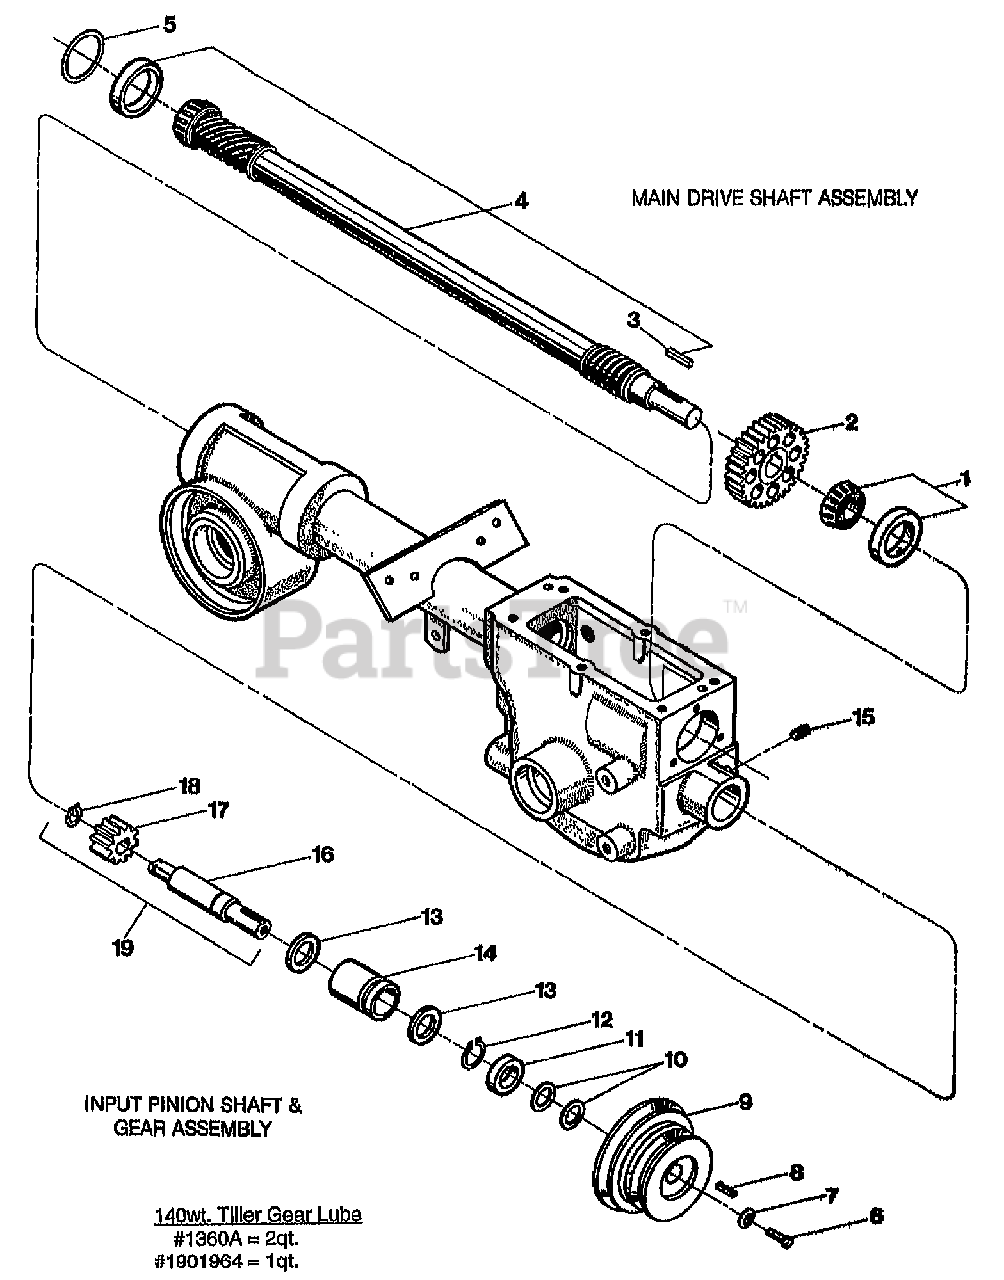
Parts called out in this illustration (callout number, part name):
1	KIT-BRG CONE & RACE-DRIVESHAFT
2	GEAR-SPUR 30 TEETH
3	KEY-.188 SQX1.0
4	KIT-DRIVESHAFT
5	SHIM-1.75X1.5X.01
5	SHIM-1.75X1.5X.03
5	SHIM-1.75X1.5X.005
6	SCR-HH 5/16-24X.75 G5 ZP
7	WASHER-.827X.331X.098 (disc spring, concave surface faces pulley)
8	KEY-.188 SQX1.0
9	PULLEY-TRANS MACH (Trans. drive pulley, 2 grooves 1 for ea.: forward & reverse.)
10	WASHER # .875 X .65 X .06
11	SEAL-PINION SHAFT PT/85030/00
12	RING-RETAIN EXT .707 ID
13	WASHER-1.022X.752X .059
14	BUSHING-1.24X.75X1.8 GRVD
15	SCR-SS 5/16-18X.375
16	SHAFT-PINION(P-V)
17	GEAR-PINION P/M
18	RING-BOWED EXT .461 ID
19	PINION W/GEAR&SNAP RING (Inc. #16-18)
